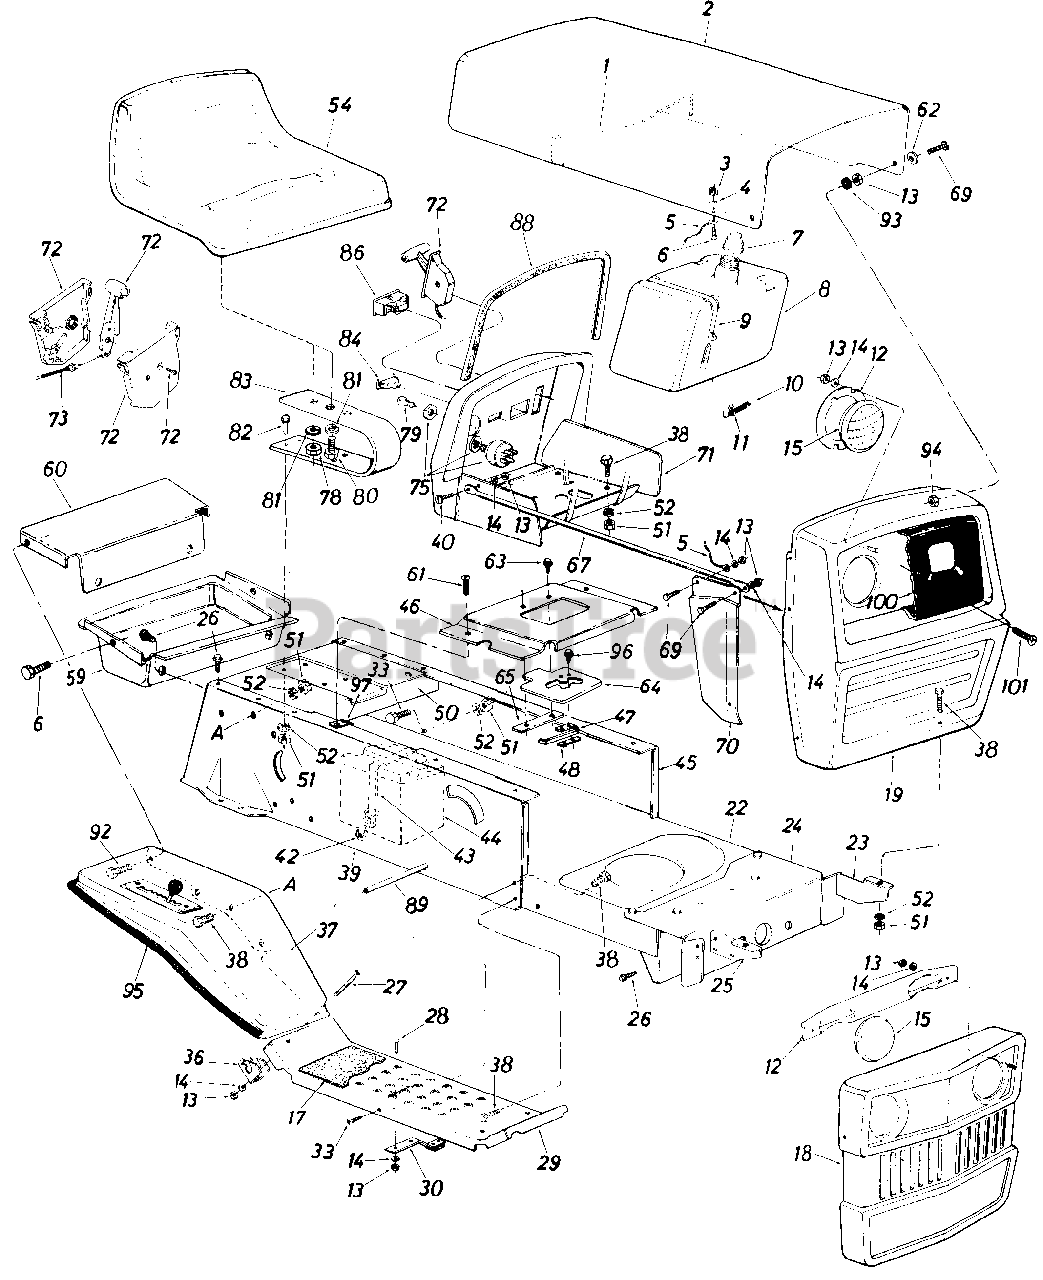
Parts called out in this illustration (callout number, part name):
1	Hood Spring
2	Hood
3	Hex Sems Nut #10-24 Thd.*
4	Fl-Wash. .281" I.D. x .62" O.D. x .051
5	Hood Stop 7" Lg.
6	Truss Hd. Scr. #10-24 x 1/2"*
7	Fuel Cap Gauge
8	Fuel Tank
9	Tie Strap
10	Fuel Line
11	Hose Clamp
12	Headlight Retainer
13	Hex Nut 1/4-20 Thd.
14	L-Wash. 1/4" I.D.
15	Headlight
17	Foot Pad
18	Grille Ass'y.
22	Lower Frame
23	Grille Mount Brkt.-L.H.
24	Front Pivot Brkt.
25	Grille Mount Brkt.-R.H.
26	Hex Wash. Hd. AB-Tap Scr. 5/16 x .75" Lg.
27	Truss Hd. Scr. 1/4-20 x 1.75" Lg.
28	Carriage Bolt 1/4-20 x .62" Lg.
29	Running Board
30	Blade Brake Ass'y.
33	Truss Mach. Scr. 5/16-18 x .75" Lg.
36	Fender Clamp
37	Fender
39	R.H. Side Frame
40	Hex Bolt 1/4-20 x .62" Lg.
42	Battery Strap Hook
43	Battery Hold Down Strap
44	12-V Battery
45	L.H. Side Frame
46	Shift Cover
47	Reverse Safety Switch
48	Insulator Nut Plate
50	Hitch Plate
51	Hex Nut 5/16-18 Thd.
52	L-Wash. 5/16" I.D.
54	Seat Ass'y.
59	Tool Tray
62	Fl-Wash. .296 I.D. x .62 O.D.
63	Truss Mach. Scr. 1/4-20 x .75" Lg.
64	Gear Selection Plate
65	Clamping Plate
67	Grille Support Rod
69	Truss Hd. Scr. 1/4-20 x .75" Lg.
70	R.H.-Grille Side Panel
71	Dash Panel Ass'y.
72	Throttle Control Box Ass'y.
73	Throttle Control Wire-B&S
75	Ignition Switch
78	Hex Nut 1/2-13 Thd.
79	Ignition Key
80	Hex Bolt 1/2-13 x 1.00" Lg.
81	L-Wash. 1/2" I.D.
82	Hex Bolt 5/16-18 x 1.00" Lg.
83	Seat Spring 5.5" High
84	Light Switch
86	Ammeter
88	Molding Strip 27" Lg.
89	Running Board Rod
92	Thread Rolling Scr. 1/4-20 x .50" Lg.
93	Rubber Wash. 1/2" I.D. x 1.0 O.D. x .25"
94	Hex Sems Ins. L-Nut 1/4-20 Thd.
95	Trim Strip
96	Hex Wash. Hd. AB-Tap Scr. #8 x .50" Lg.
97	Speed Nut #lOZ
100	Bezel
101	Truss Scr. #10-24 x .62" Lg.
